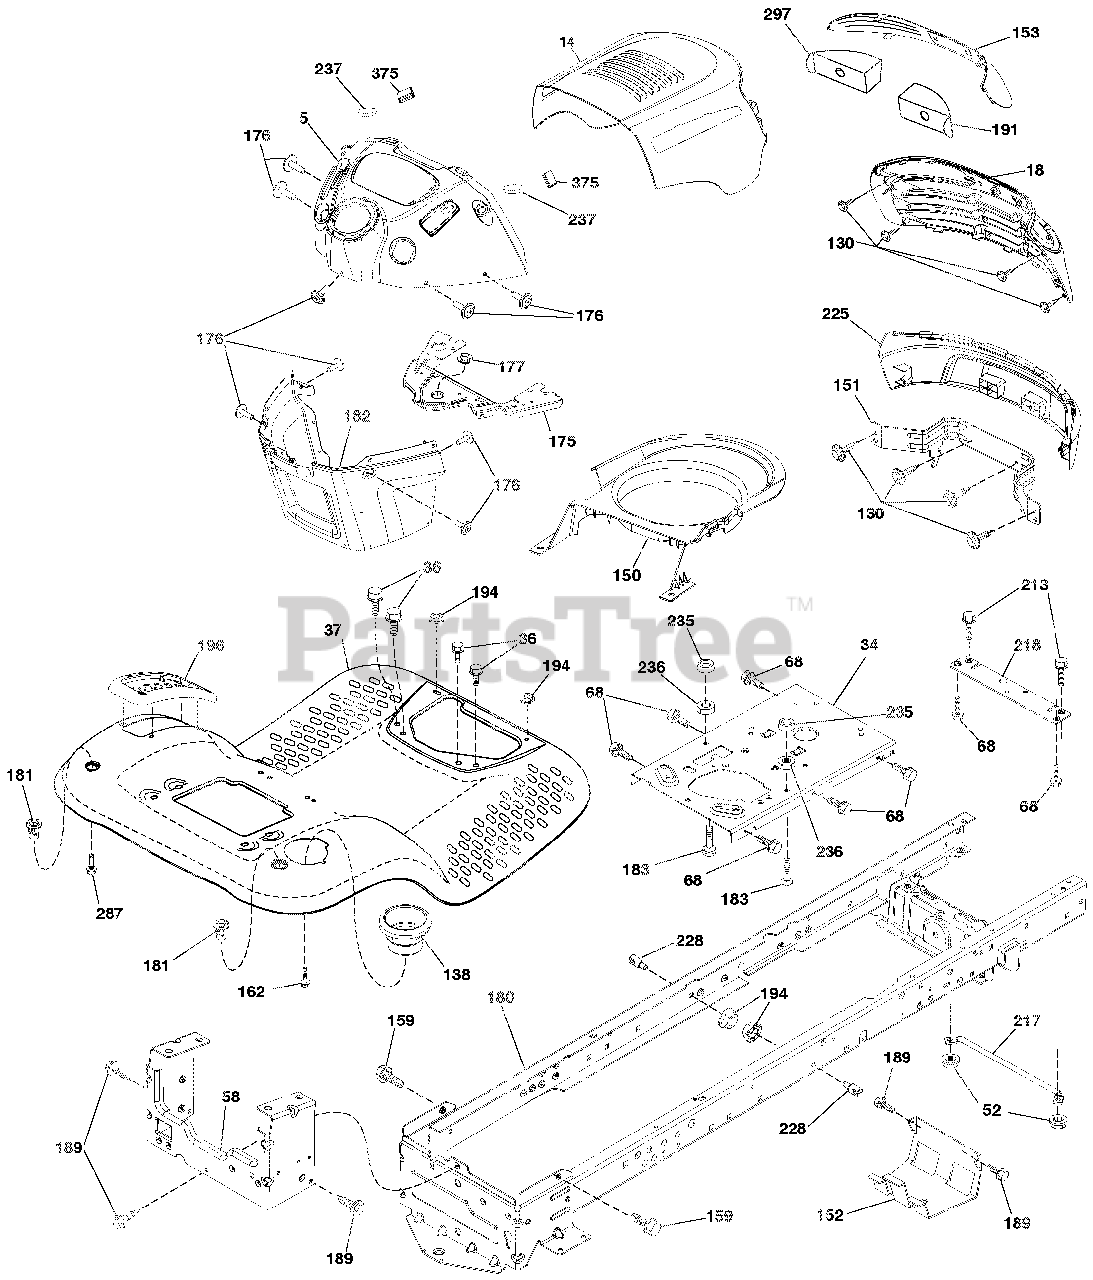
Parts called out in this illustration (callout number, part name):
18	GRILLE
34	PLATE.ENGINE.WELDED.CHASSIS
36	SCREW.5/16-18X3/4.SMGML.TAP/R
37	FENDER.TLT W/CPH
52	Nut, Hex, Crownlock 5/16-18
58	DRAWBAR.UPPER.2PC.SML.FENDER
68	SCREW.THDROL.5/16-18 X 1/2TYTT
138	CUPHOLDER TL TEX 428
150	AIR DUCT.INTAKE.B&S
151	Bracket Pivot
152	SHIELD.BROWNING.W/TEX
153	LENS, ARIENS
159	SCREW.HEXWSH THDR3/8-16X3/4.BL
162	SCREW.HEX.WSH.HI-LO.1/4X1/2UNC
175	CROSSMEMBER.LT
176	SCREW.#10-24X5/8.RND.QUDRX.GIM
177	BUSHING.STEERING.LT
180	CHASS.WLDMT.TL.12GA/2PC.18/22"
181	BUSHING MNT FEND CRGO BLK TEX
182	DASH LOWER
183	BOLT.FIN.HEX.5/16-18 UNC X1-1/
189	SCREW.5/16-18X3/4.SMGML.TAP/BL
191	INSERT REFLECTIVE RH
194	Nut, Lock Hex Flange 5/16-18 u
196	CONSOLE ASSEMBLY
213	Bolt, Hex Head 5/16-18 x 3/4
217	ROD.PIVOT.HOOD
218	X-PIECE.HOOD.STOP.NON/STEALTH
225	BUMPER
228	STUD.FASTNER.W/'D'ANTI-ROTATIO
235	SPACER.FENDER
236	NUT.CENTER LOCK.5/16-18 UNC
237	PLUG.MOUNT.CARGO
287	SCREW.HEX.WASHEAD.1/4-20 X 3/8
297	INSERT REFLECTIVE LH
375	DASH CLIP - ON BUMPER
